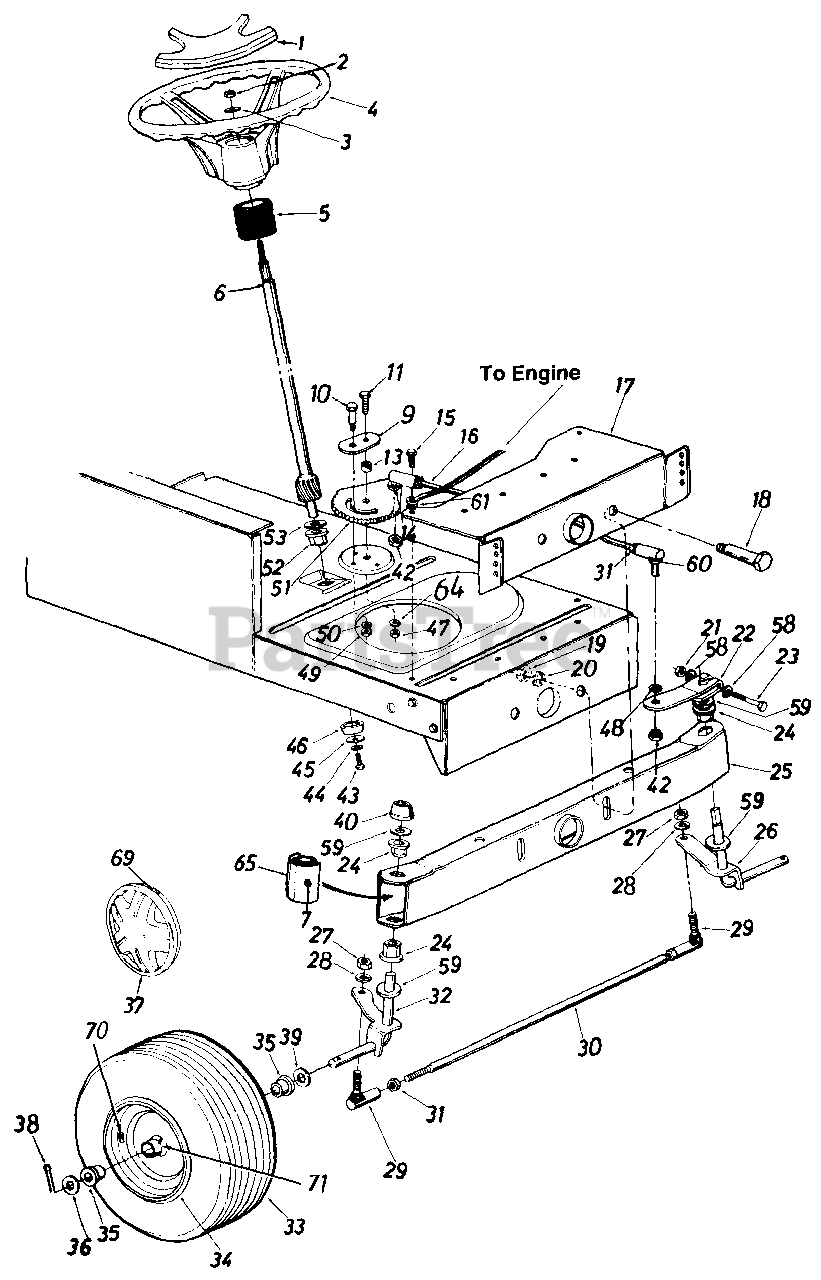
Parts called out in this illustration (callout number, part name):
1	Steering Wheel Insert
2	Hex L-Nut 5/16-24 Thd.
3	Belleville Wash. .345" I.D.
4	Steering Wheel
5	Steering Bellow
6	Steering Shaft
7	Grease Fitting
9	Retainer Plate
10	Shoulder Bolt .437" Dia. x .35" Lg. 5/16-18 Thd.
11	Hex Bolt 3/8-24 x 1.0" Lg. (Grade 5)
13	Spacer .380" I.D. x .625" O.D. x .227"
14	L-Wash. 3/8" I.D.
15	Hex Wash. Hd. Self-Tap Scr.
16	Steering Drag Link
17	Front Pivot Brkt.
18	Shoulder Bolt .498" Dia. x 2.04" Lg. 3/8-16 Thd.
19	Hex Nut 3/8-16 Thd.
20	L-Wash. 3/8" I.D.
21	Hex Cent. L-Nut 5/16-24 Thd.
22	Steering Arm Front Axle
23	Hex Bolt 5/16-24 x 2.00" Lg. (Grade 5)
24	Hex Flg. Brg. .632" I.D.
26	Front Axle Ass'y. - L.H.
27	Hex Nut 3/8-24 Thd.
28	L-Wash. 3/8" I.D.
29	Ball Joint 3/8-24 Thd.
31	Hex Jam Nut 3/8-24 Thd.
32	Front Axle Ass'y. - R.H.
36	Fl-Wash. .635" I.D. x 1.59" O.D.
37	Hub Cap
38	Cotter Pin 1/8" Dia. x 1.25" Lg.
39	Fl-Wash. .640" I.D. x .24" O.D.
42	Hex Jam Nut 3/8-24 Thd.
43	Hex L-Bolt 5/16-18 x .62"
44	L-Wash. 5/16" I.D.
45	Fl-Wash. .33" I.D. x 1.25" O.D.
46	Spacer (Plastic)
47	Hex Cent. L-Nut 3/8-24 Thd.
48	L-Wash. 3/8" I.D.
49	Hex Cent. L-Nut 5/16-18 Thd.
50	L-Wash. 5/16" I.D.
51	Steering Gear Segment
52	Hex Flg. Brg. .634 I.D.
53	Fl-Wash. (Hardened)
58	Wave Wash. .32" I.D. x .62"
59	Fl-Wash. (Hardened)
60	Drag Link Ball Joint 3/8-24 Thd.
61	Ext. L-Wash. 5/16" I.D.
65	Pivot Bar End Cap
69	Spring Clip
70	Air Valve
71	Grease Fitting
